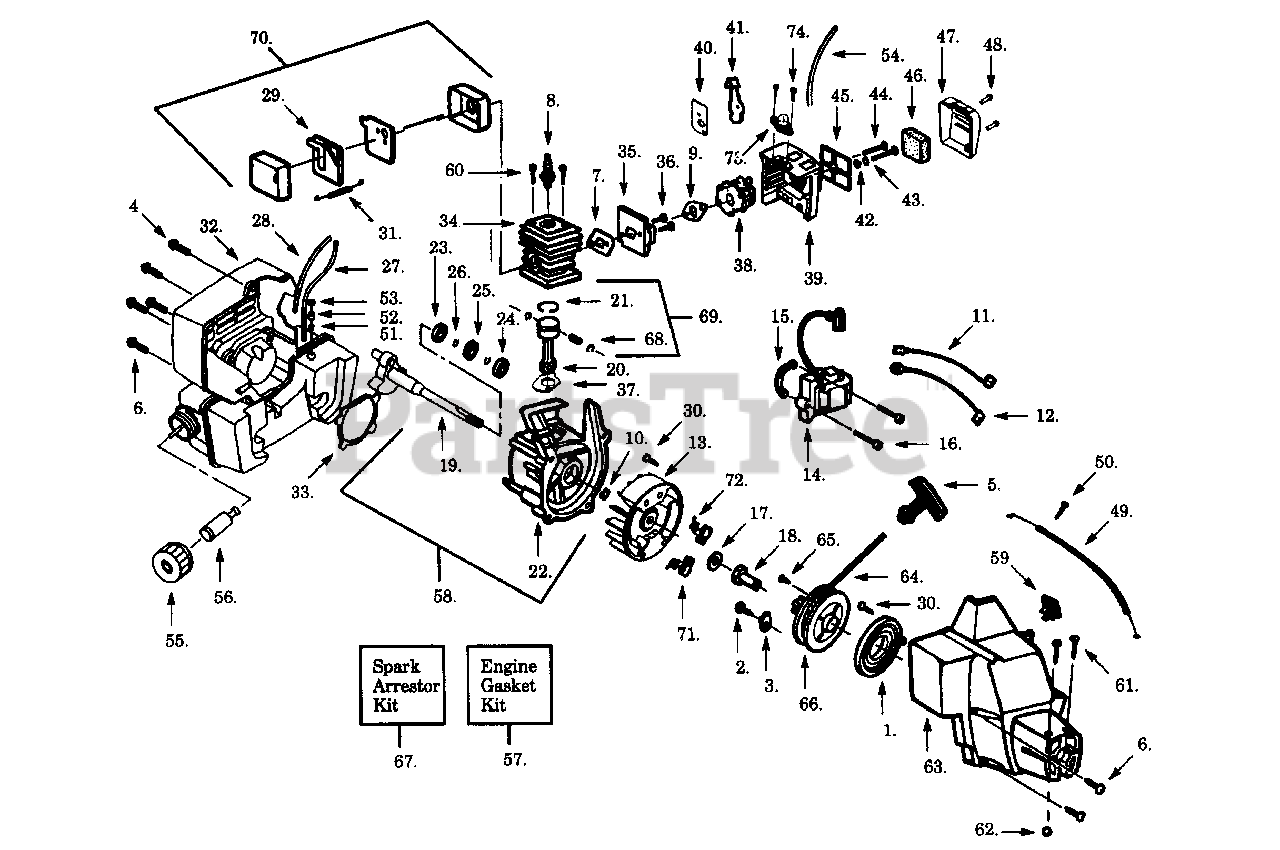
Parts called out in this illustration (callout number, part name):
1	Starter Spring
2	Screw-Pulley
3	Retainer-Pulley
4	Screw-Shrd./Fan Hsg.
5	Starter Handle
6	Screw-Fan Hsg.
7	Gasket-Cylin./Carb.
8	Spark Plug
9	Gasket-Carb.
10	Retainer-C'Case
11	Lead Wire
12	Ground Wire
13	Flywheel Ass'y.
14	Ignition Module
15	Spacer-Ignition Mod.
16	Screw-Ignition Mod.
17	Washer-Flysheel
18	Drive Coupling
19	Crankshaft Ass'y.
20	Connecting Rod Ass'y.
21	Piston Ring
22	Crankcase Ass'y.
23	Inner Bearing
24	Outer Bearing
25	C'case Seal
26	Retain. Ring-C'shaft
27	Fuel Line-Prim.Tnk.
28	Fuel LIne-Carb./Tnk.
29	Muffler Baffle-Exit
30	Screw-Flywheel
31	Muffler Spring
32	Shroud & Tank Assy., LT7000 Type 1
32	Shroud & Tank Assy., LT17 & LT7000 Type 2
33	Gasket-C'case
34	Cylinder
35	Carb. Adaptor Kit, LT17
37	Gasket-Cylinder
38	Carburetor, LT7000 Type 1 (WA-215)
38	Carburetor, LT17 & LT7000 Type 2 (WA-218 w/Limiter Cap)
39	Air Box, LT7000 Type 1
39	Air Box, LT17 & LT7000 Type 2
40	Choke Plate
41	Choke Shutter
42	Wave Washer
43	Choke Spacer
44	Screw-Carb.
45	Filter Plate
46	Air Filter Foam
47	Air Filter Cover
48	Screw-Filter Cover
49	Throttle Cable Ass'y.
50	Screw-Carb. Adaptor
51	Check Valve
53	Retainer
54	Fuel Line-Prim./Carb.
55	Fuel Cap Ass'y.
56	Fuel Pickup Ass'y.
57	Engine Gasket Kit
58	C'case & C'shaft Assy.
59	On/Off Switch
60	Screw-Cylinder
61	Screw-Pinch Clamp
62	Locknut-Pinch Clamp
63	Fan Housing
64	Rope Kit
65	Screw-Rope Retain.
66	Starter Pulley Kit
67	Spark Arrestor Kit
68	Piston Pin Retainer
69	Piston Kit
70	Muffler Kit
71	Starter Dog
72	Starter Spring
73	Primer Bulb Ass'y. LT17 & LT7000 Type 2
74	Screw-Primer LT17 & LT7000 Type 2
